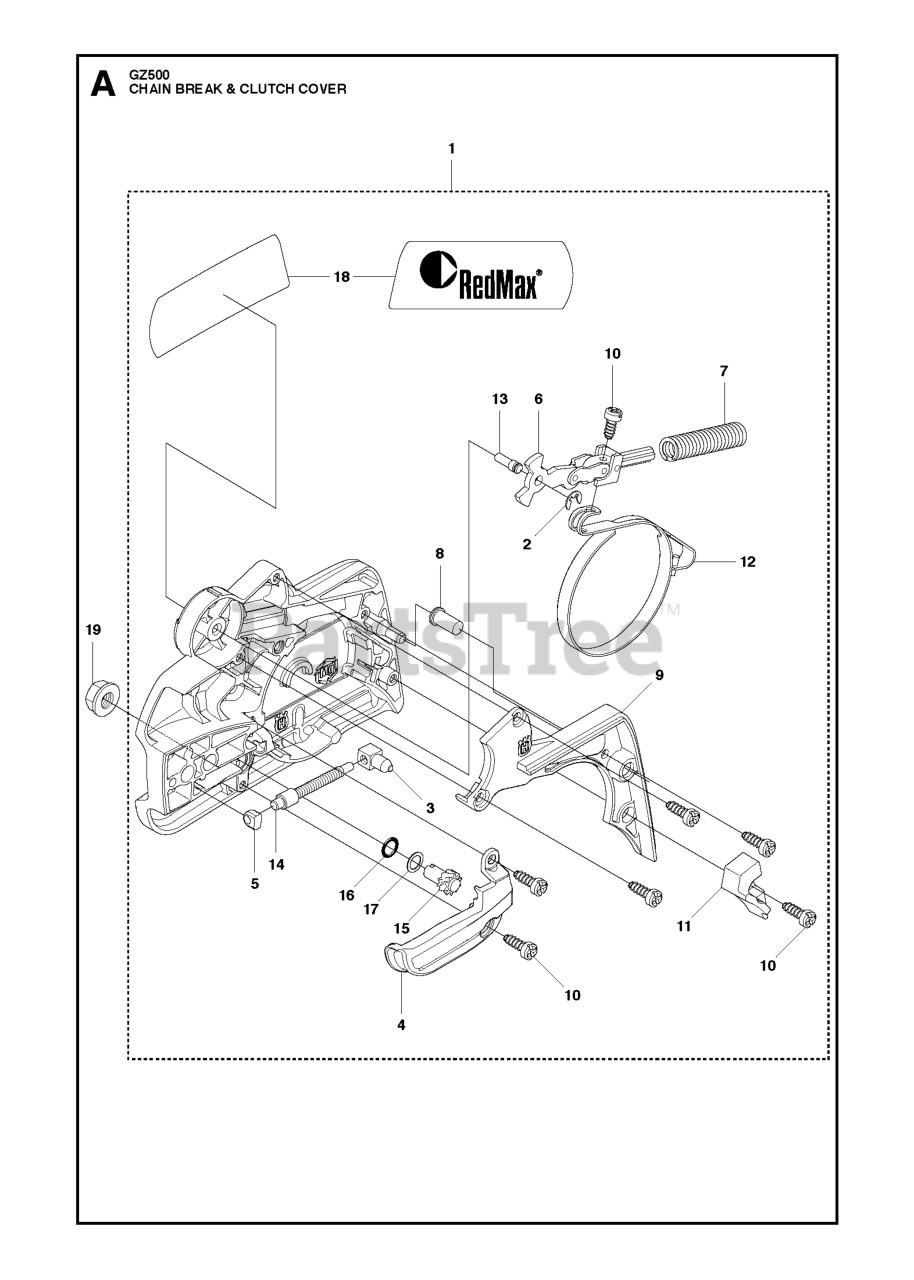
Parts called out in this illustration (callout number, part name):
1	CLUTCH COVER ASSY STD REDMAX
2	E-RING 4
4	CHAIN GUIDE
5	BEARING SLEEVE
6	KNEE JOINT ASSY
7	BRAKE SPRING
8	GUIDE BUSHING
9	COVER, CHAIN BRAKE
10	SCREW CCRPANT
11	WEAR GUARD, CHAIN
12	BRAKE BAND ASSY
13	PIN KNEE JOINT
15	WORM WHEEL
17	WASHER STEEL
18	LABEL CLUTCH COVER REDMAX
19	NUT M8 FLANGE
